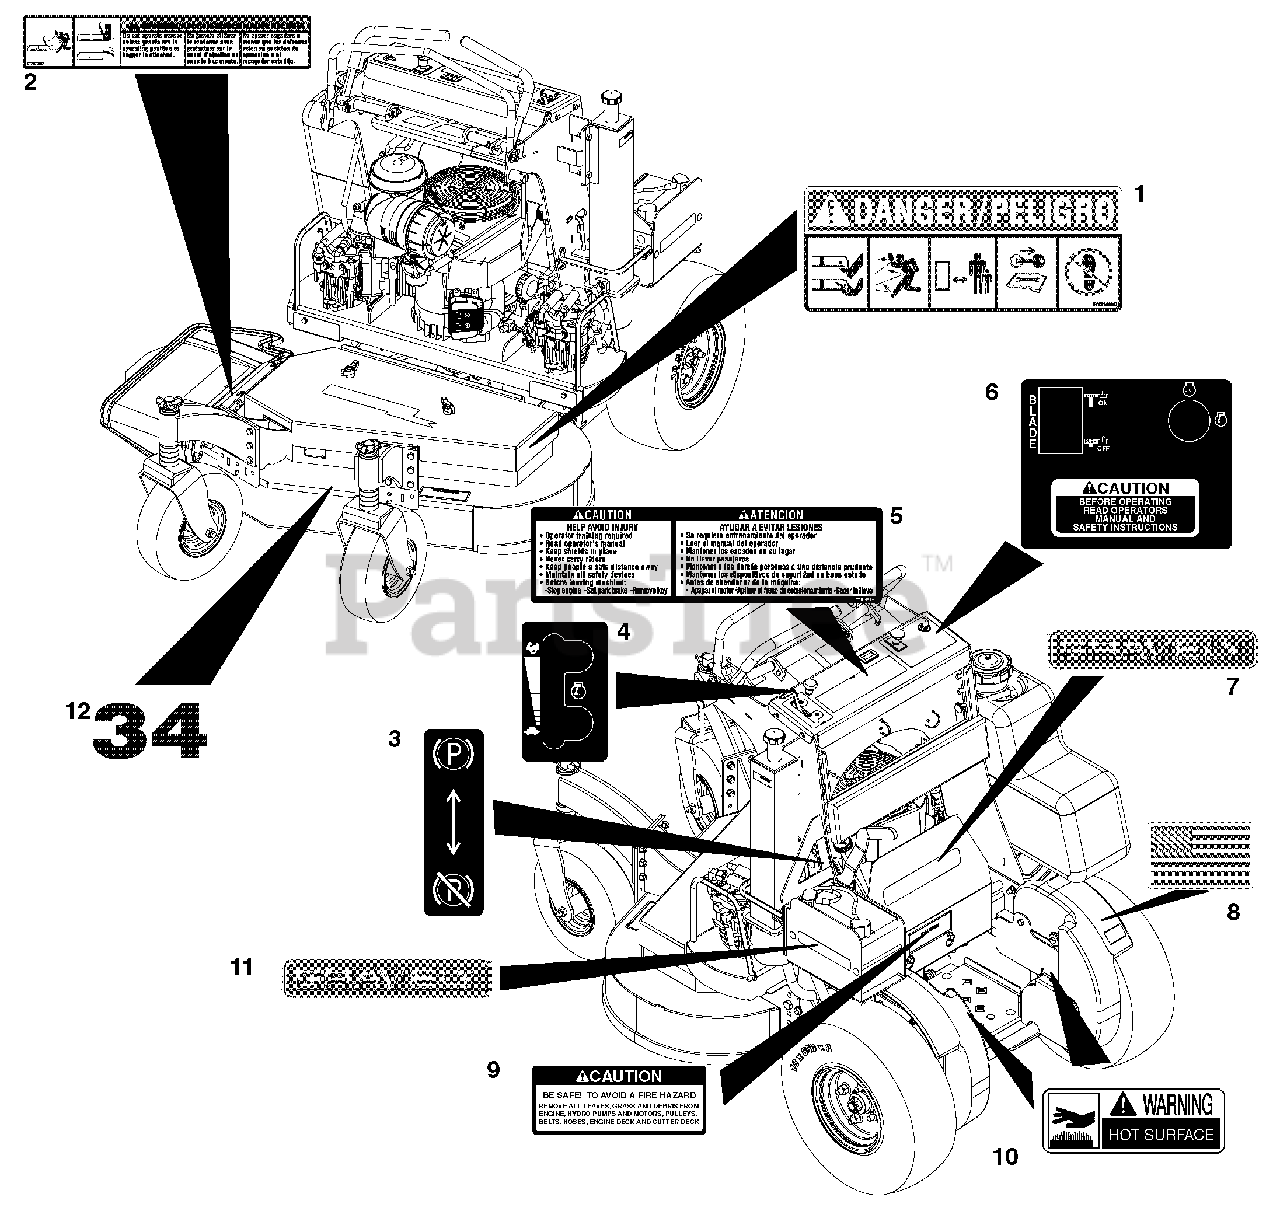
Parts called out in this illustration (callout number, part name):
1	Decal, Danger - Blade Contact
2	Decal, Danger - Rotating Blades
3	Decal, Park Brake
4	Decal, Throttle
5	Decal, General Caution
6	Decal, PTO/Ignition
7	Decal, 15" Gravely Logo
8	Decal, American Flag
9	Decal, Caution - Fire Hazard
10	Decal, Warning, Hot Surface
11	Decal, Gravely Logo
12	Decal, 34"
